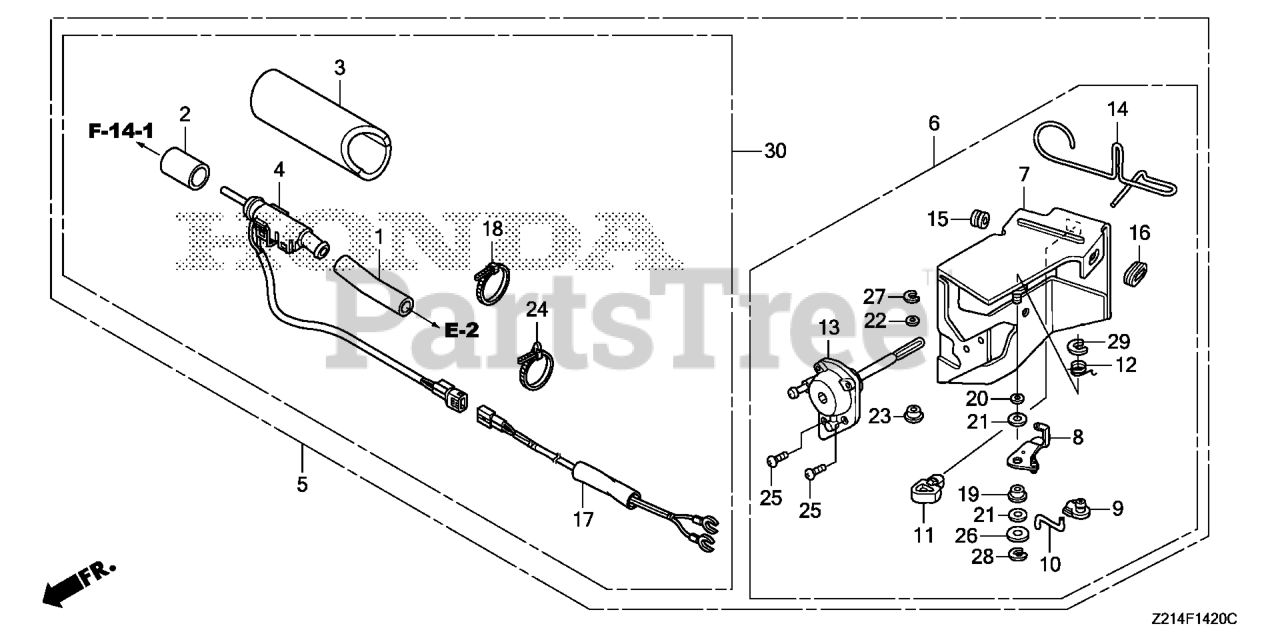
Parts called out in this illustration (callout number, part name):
1	TUBE, BREATHER (NOT AVAILABLE)
2	TUBE B, BREATHER
3	INSULATOR, BREATHER TUBE (NOT AVAILABLE)
4	HEATER ASSY., BREATHER (S) (NOT AVAILABLE)
17	SUB-WIRE ASSY.
18	TIE, CABLE (C)
24	CLIP, HARNESS BAND (145MM) (BLACK)
30	HEATER KIT, BREATHER
